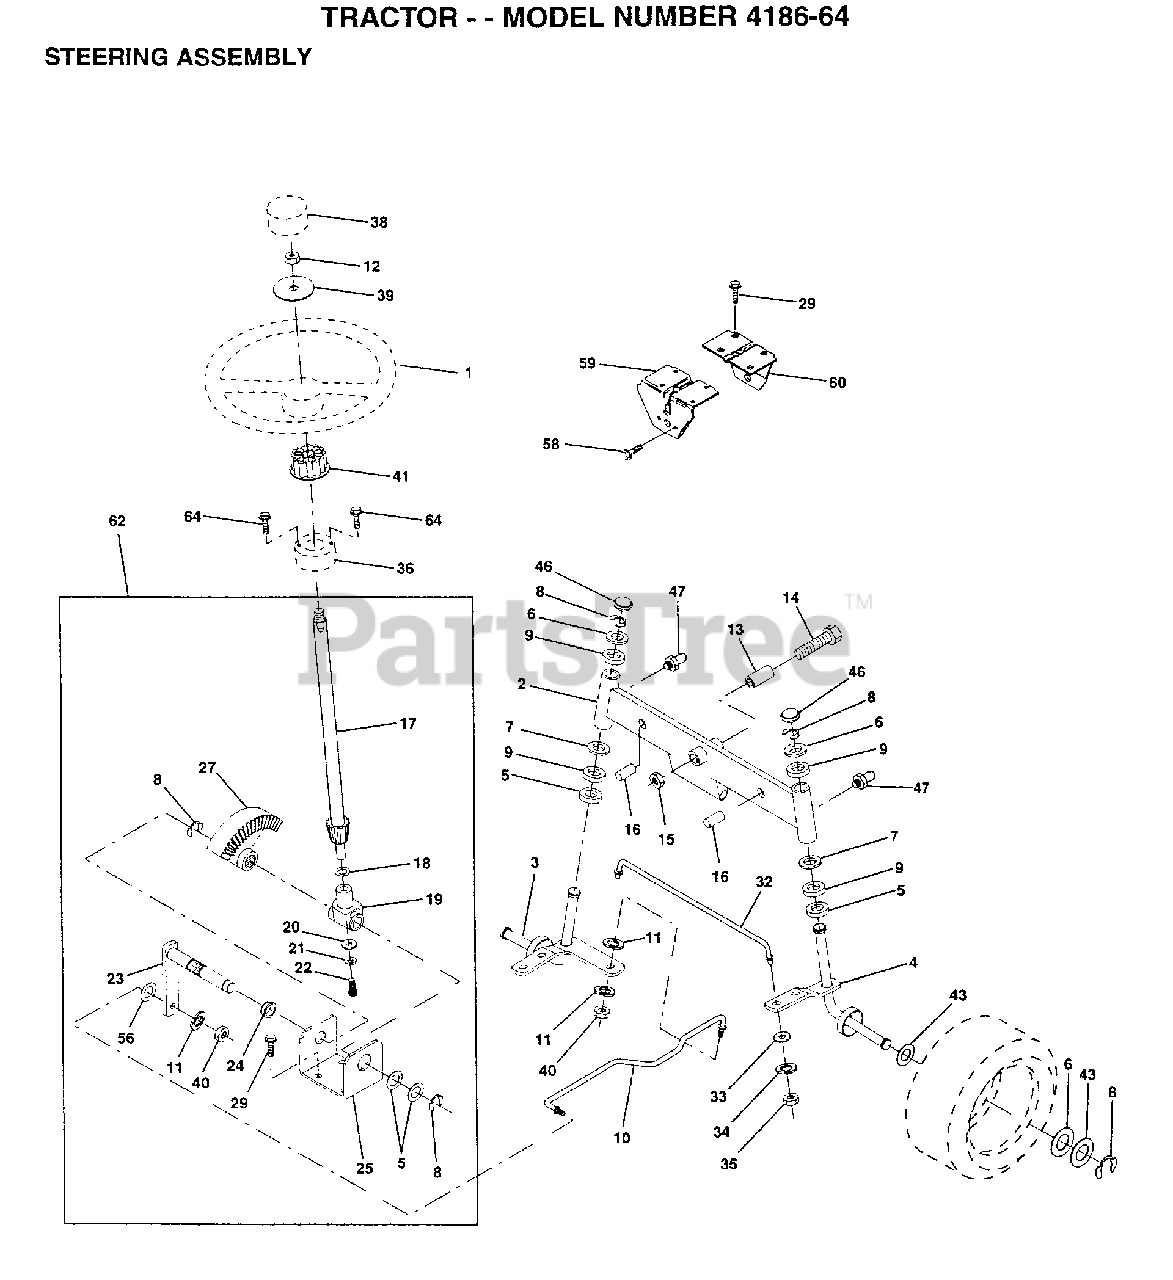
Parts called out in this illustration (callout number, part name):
2	AXLE ASM FRONT
3	SPINDLE LH
4	SPINDLE RH
5	WASHER .T
6	WASHER
7	WASHER
8	RING
9	COL. SRTG. BEAR.
11	LOCKWASHER
13	BEARING
14	BOLT LT
15	"NUT-LOC,FLANGE LT"
16	AXLE PIN
18	THRUST WASHER
19	SUPPORT.SHAFT
21	LOCKWASHER
22	SCREW.SCKTHD.CAP
24	NYLINER T
25	"BRKT,STEERING"
27	GEAR SECTOR
29	SCREW
32	TIE ROD
33	WASHER M
34	LOCKWASHER
35	NUT.LOCK.5/16-24
36	BUSHING.STRG.3/4
38	"INSERT,STR WHEEL"
39	WASHER
40	GRIPCO NUT
41	ADAPTER LT
43	WASHER
46	CAP
47	ZERK M
56	WASHER
58	SCREW LT
59	SUPPORT-SADDL T
60	SUPPORT.SADDLE.FT
62	KIT.STEER.20.31
64	"SCREW-TT,10-32 FL"
